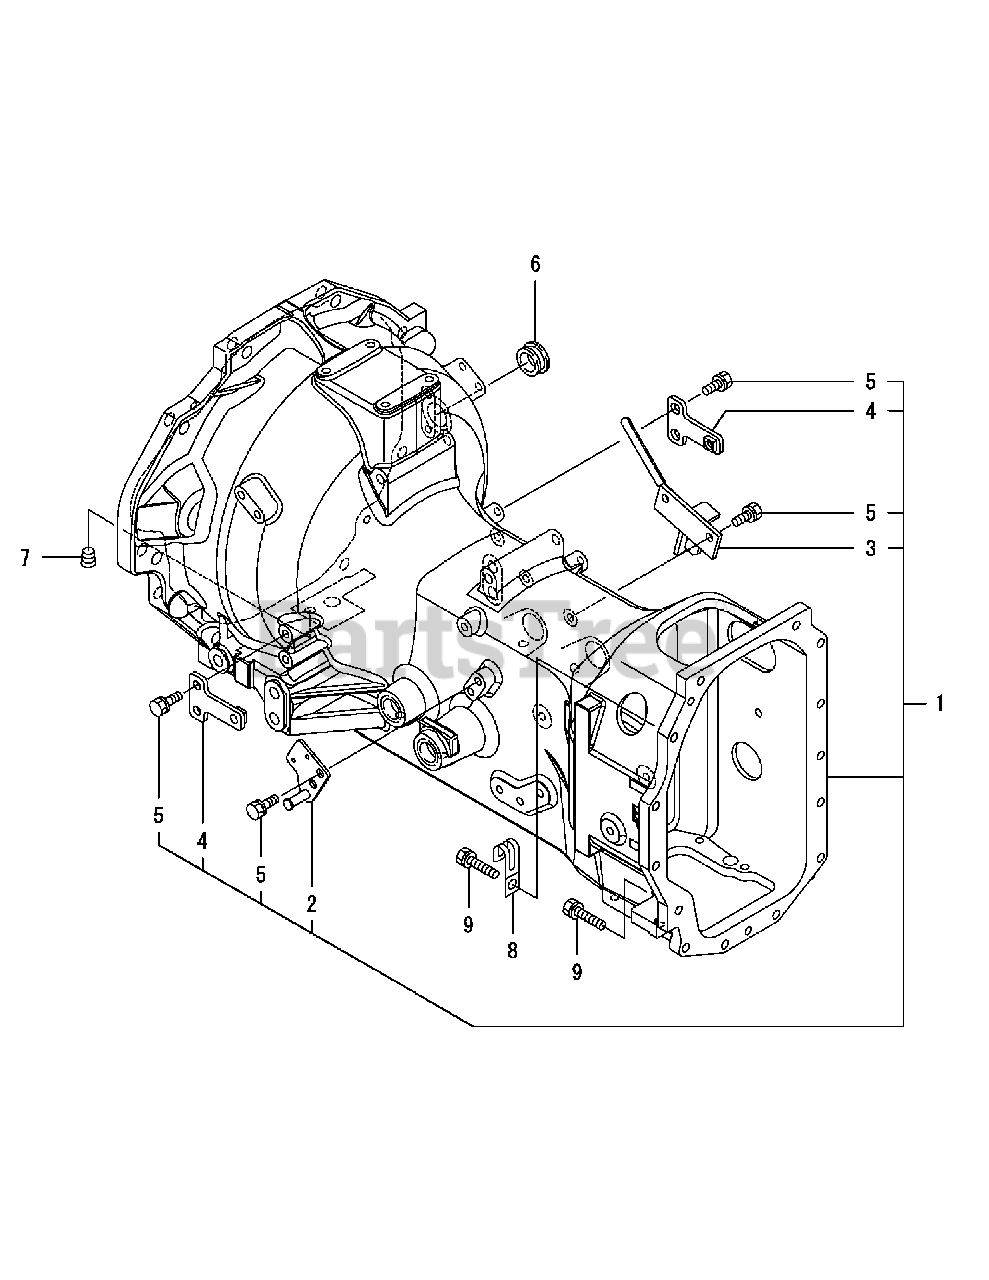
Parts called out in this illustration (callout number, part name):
1	Housing Assy, Clutch
2	Stay Cmp, Switch
4	Stay, F Rest L
6	Rubber, Cap 25
8	Clamp,Battery Cable
